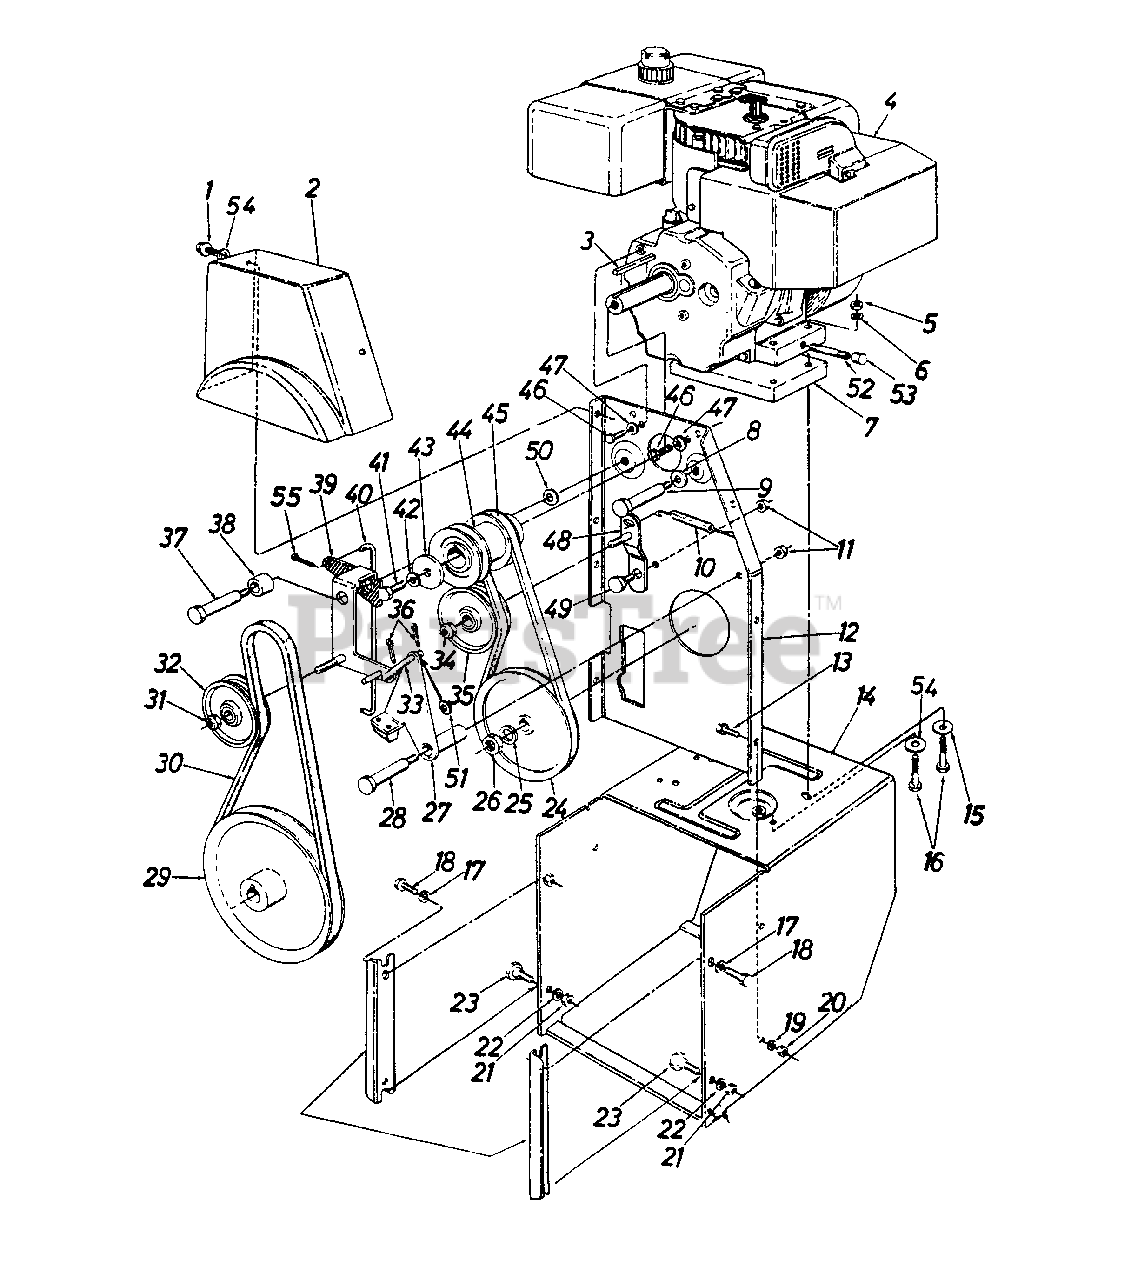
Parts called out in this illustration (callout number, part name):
1	Hex Wash. HD S-Tap Scr. 5/16-18 x .50
2	Plastic Belt Cover
3	Sq. Key 1/4 x 1/4 X 1.50" Lg.
4	Engine
5	Hex Nut 5/16-18
6	L-Wash. 5/16 I.D.
7	Engine Spacer Ass'y.
8	Bell-Washer .400 I.D. x .88 O.D. x .06
9	Shoulder Screw .498 Dia. x 3.00
10	Brake Return Extension Spring 3.18" Lg.
11	Hex Cent. L-Nut 3/8-16
12	Engine Plate Ass'y.
13	Hex Sems Scr. 5/16-18 x .75
16	Hex Bolt 5/16-18 x 2.25
17	Lock Washer Heavy 3/8" I.D.
18	Hex Pilot Screw 3/8-16 x .88" Lg.
19	L-Wash. 5/16 I.D.
20	Hex Nut 5/16-18
21	Hex Nut 3/8-16
22	Lock Washer Heavy 3/8" I.D.
23	Shld. Scr. .500 Dia. x .335" Lg.
24	1/2" "V" Pulley .625 I.D. x 7.50 O.D.
25	Lock Washer 5/16 I.D.
26	Hex Ins. Jam Lock Nut 5/8-18
27	Brake Brkt. Ass'y.
28	Axle Bolt
29	1/2" V-Pulley .875 I.D. x 10.12 O.D.
30	V-Belt 1/2 X 45.0" Lg.
31	Hex Nut 3/8-24
32	Flat ldler w/Flanges 3.0 O.D.
33	Sliding Rod .31 Dia. x 2.0" Lg.
34	Hex Nut 3/8-24
35	Flat ldler w/Flanges 3.0 O.D.
36	Cotter Pin 3/32 x .75
37	Shoulder Screw .625 Dia. x 2.75
38	Spacer .64 I.D. x .75 O.D. x 1.0" Lg.
41	Hex Screw 3/8-24 x 1.25
42	Lock Washer Heavy 3/8" I.D.
43	Flat Washer .39 I.D. x 1.75 O.D. x .175
44	Double Groove Engine Pulley (w/8 HP Tec)
45	V-Belt 1/2 X 35.5" Lg.
46	Hex Screw 5/16-24 x .62
47	Bell-Washer 400 I.D. x .88 O.D. x .06
48	Drive Idler Brkt. Ass'y.
49	Shoulder Scr. .625 Dia. x .170
50	Bell-Washer .406 I.D. x 1.12 O.D.
51	Flat Washer .34 I.D. x .62 O.D. x .03
52	Drain Pipe 1/4" NP
54	Flat Washer .344 I.D. x .625 O.D. x .063
55	Cotter Pin 3/32 x .75
